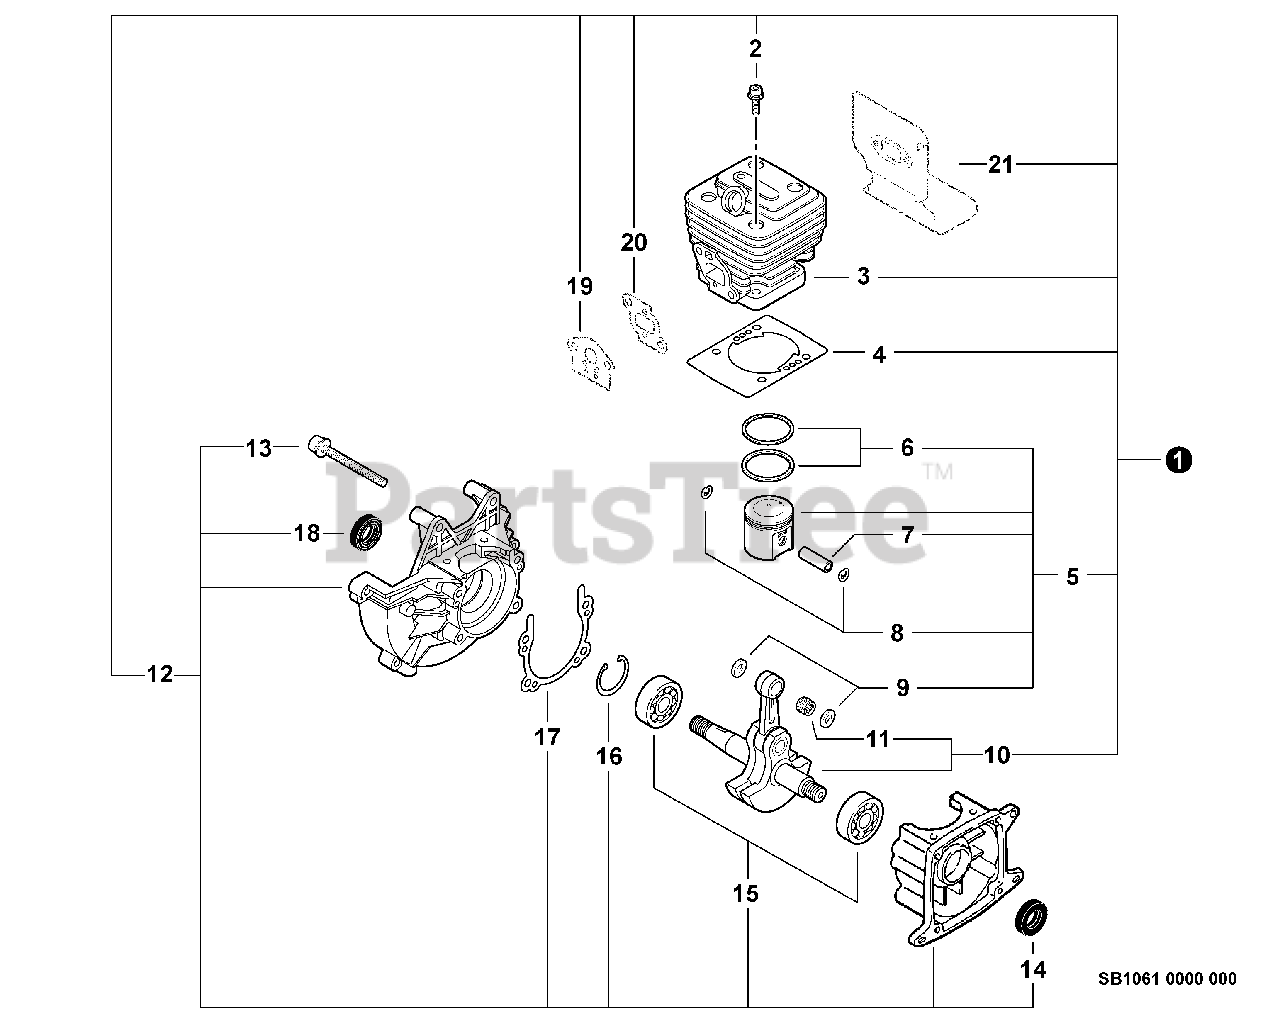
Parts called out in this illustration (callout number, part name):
1	SHORT BLOCK -- SB1061
2	SCREW - 5X22
3	CYLINDER
4	GASKET, CYLINDER
5	PISTON KIT
6	RING, PISTON
7	PIN, PISTON
8	RING, RETAINING
9	SPACER, PISTON
10	CRANKSHAFT ASSY
11	BEARING, NEEDLE - 8
12	CRANKCASE KIT
13	SCREW - 5X25
14	SEAL, OIL
15	BEARING, BALL - 6001C3
16	RING, RETAINING - 28
17	GASKET, CRANKCASE
18	SEAL, OIL - 12
19	SHIELD, EXHAUST
20	GASKET, INTAKE
21	GASKET, INTAKE
